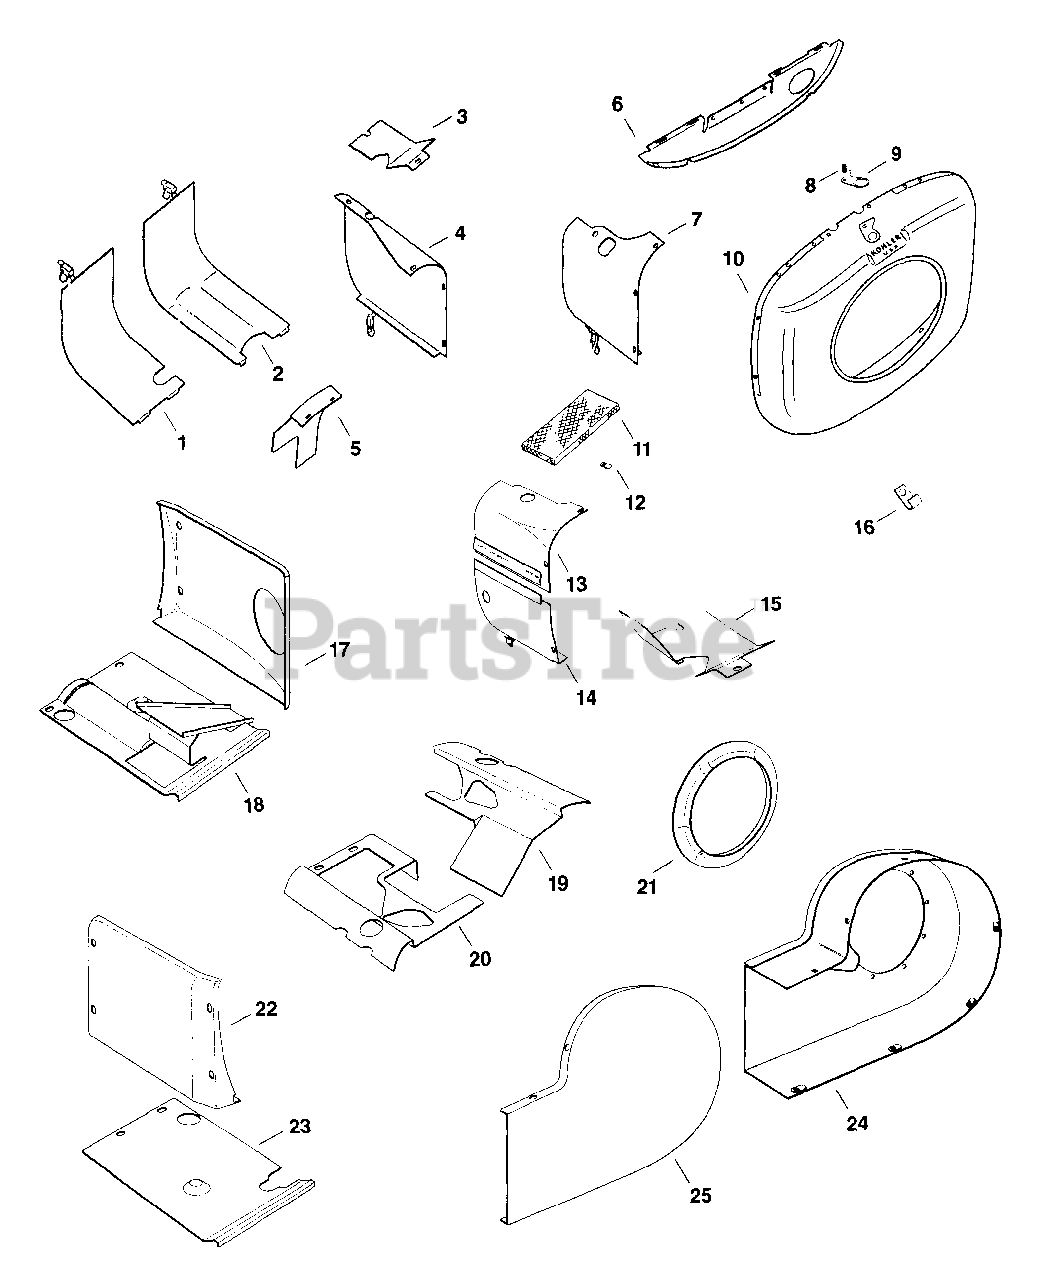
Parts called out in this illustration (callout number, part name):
1	BAFFLE - (#DSC)
5	BAFFLE - DISCONTINUED
6	BAFFLE - DISCONTINUED
7	BAFFLE - (#DSC)
16	CLIP, CABLE
